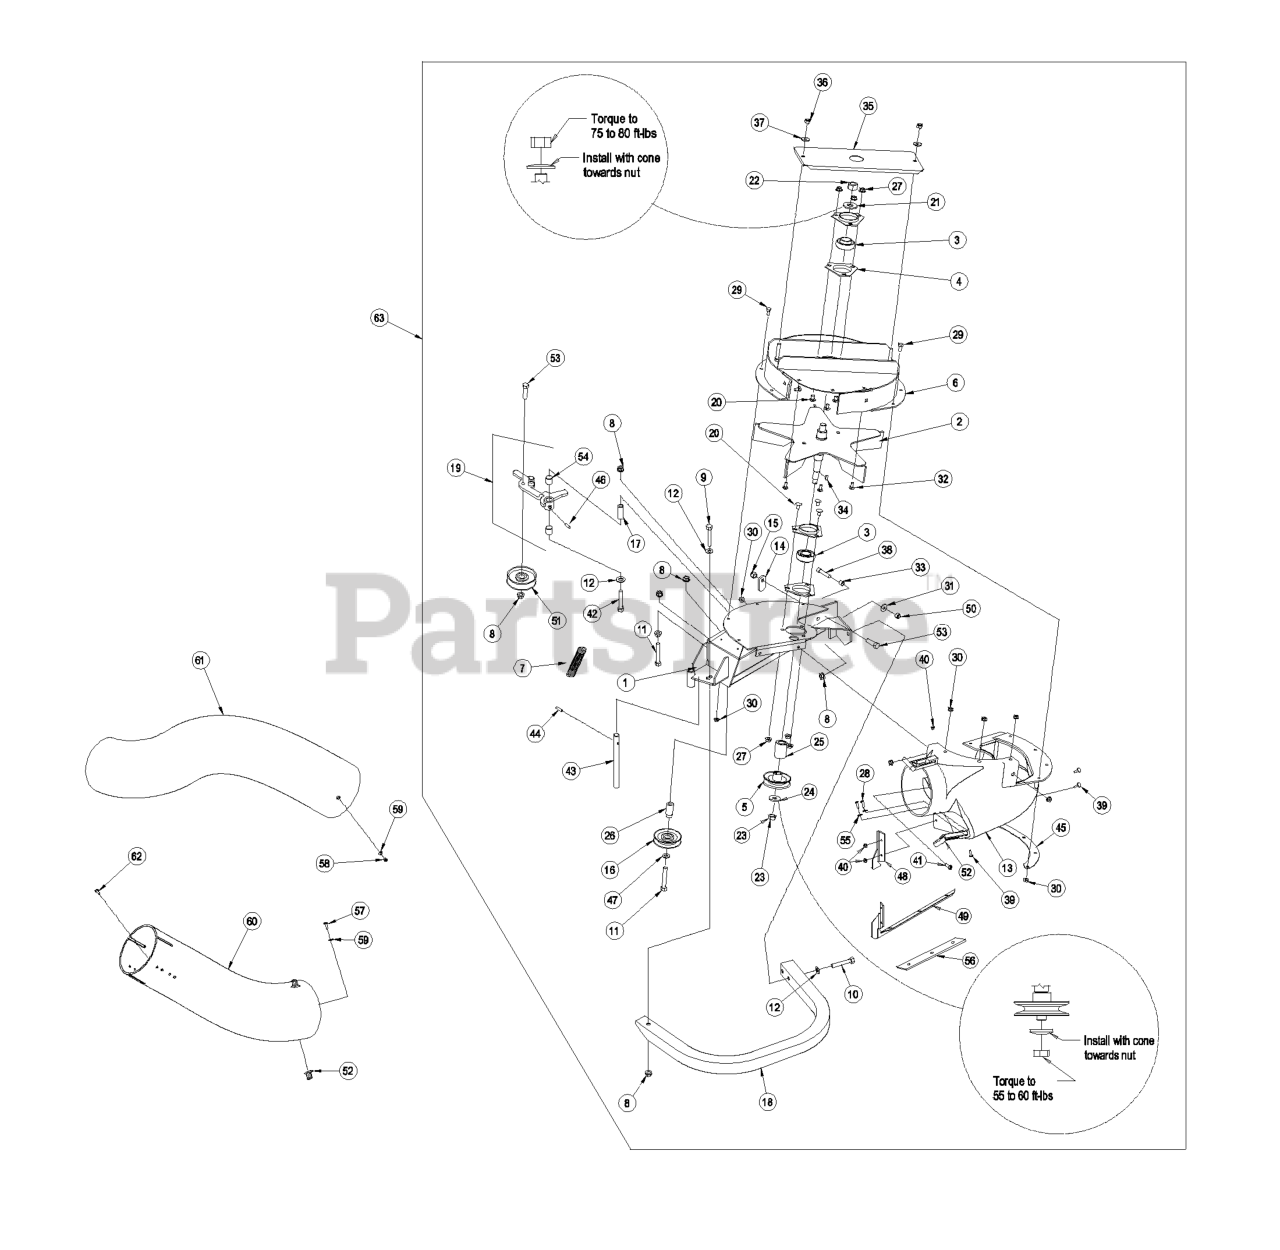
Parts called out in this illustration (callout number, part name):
1	WLD,BLOWER MOUNT
2	IMPELLER
3	BEARING
4	HOUSING-FLANGE
5	SHEAVE-BLOWER
6	ASM, UPPER HOUSING LZUV52
7	SPRING-IDLER
8	NUT-HHF, WHIZ
9	SCREW-HH
10	SCREW-HH
11	BOLT-CARR
12	WASHER-FLAT
13	CHUTE-BLOWER, SMALL
14	LATCH-CATCHER, GRASS
15	NUT-LOCK, NI
16	IDLER-INSIDE
17	BUSHING-PIVOT, IDLER
19	ASM, IDLER ARM - SERVICE
20	SCREW-CARR
21	WASHER-SPRING
22	NUT-HEX
23	NUT-JAM
24	WASHER-SPRING
28	SCREW-PPH
29	SCREW-HH
31	WASHER-SPRING
32	SCREW-CARR
33	BUSHING, LOCATOR
34	KEY-WOODRUFF
35	ASM, BEARING COVER
36	NUT-LOCK, NI
37	WASHER-FLAT
38	SCREW-HSH
39	SCREW-HEAD, TRUSS
42	SCREW-HSBH
43	SHAFT-CATCHER, GRASS
44	PIN-ROLL
45	PLATE-BACKING, BLOWER
46	FITTING-GREASE
47	WASHER-FLAT
48	PLATE, FILLER
49	PLATE, BLOCKER
50	NUT-HEX
51	IDLER-FLAT
52	LATCH DRAW
53	SCREW-HH
54	BUSHING
55	WASHER-FLAT
56	PLATE-REINFORCEMENT
57	SCREW-PPH
58	NUT-LOCK, NI
59	WASHER-FLAT
60	KIT,LOWER TUBE
61	TUBE-UPPER
62	SCREW-HWH
63	ASM, BLOWER LZUV52 - SERV
